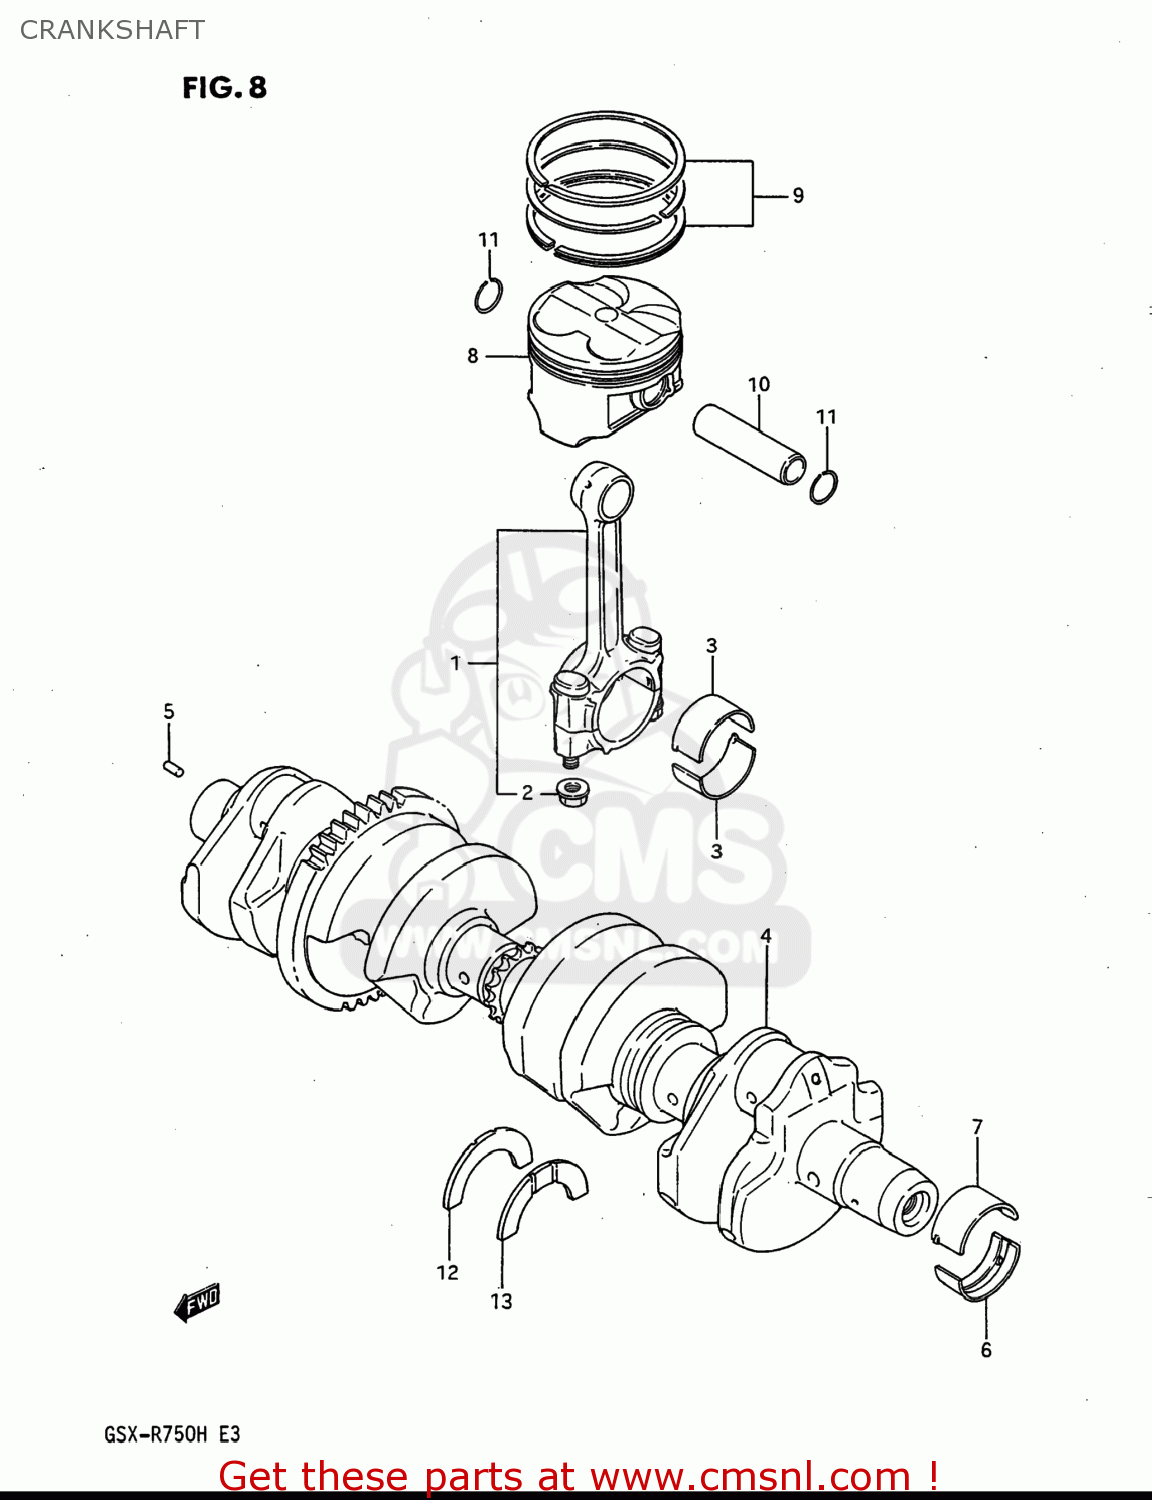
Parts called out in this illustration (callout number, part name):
1	ROD ASSEMBLY,CONNECTING
2	NUT
3	BEARING,CRANK PIN
4	CRANKSHAFT
5	PIN
6	BEARING,CRANKSHAFT LWR
7	BEARING,CRANKSHAFT UPR
8	PISTON
9	RING SET,PISTON
10	PIN,PISTON
11	CIRCLIP
12	PLATE,CRANK THRUST
13	PLATE,CRANK THRUST
